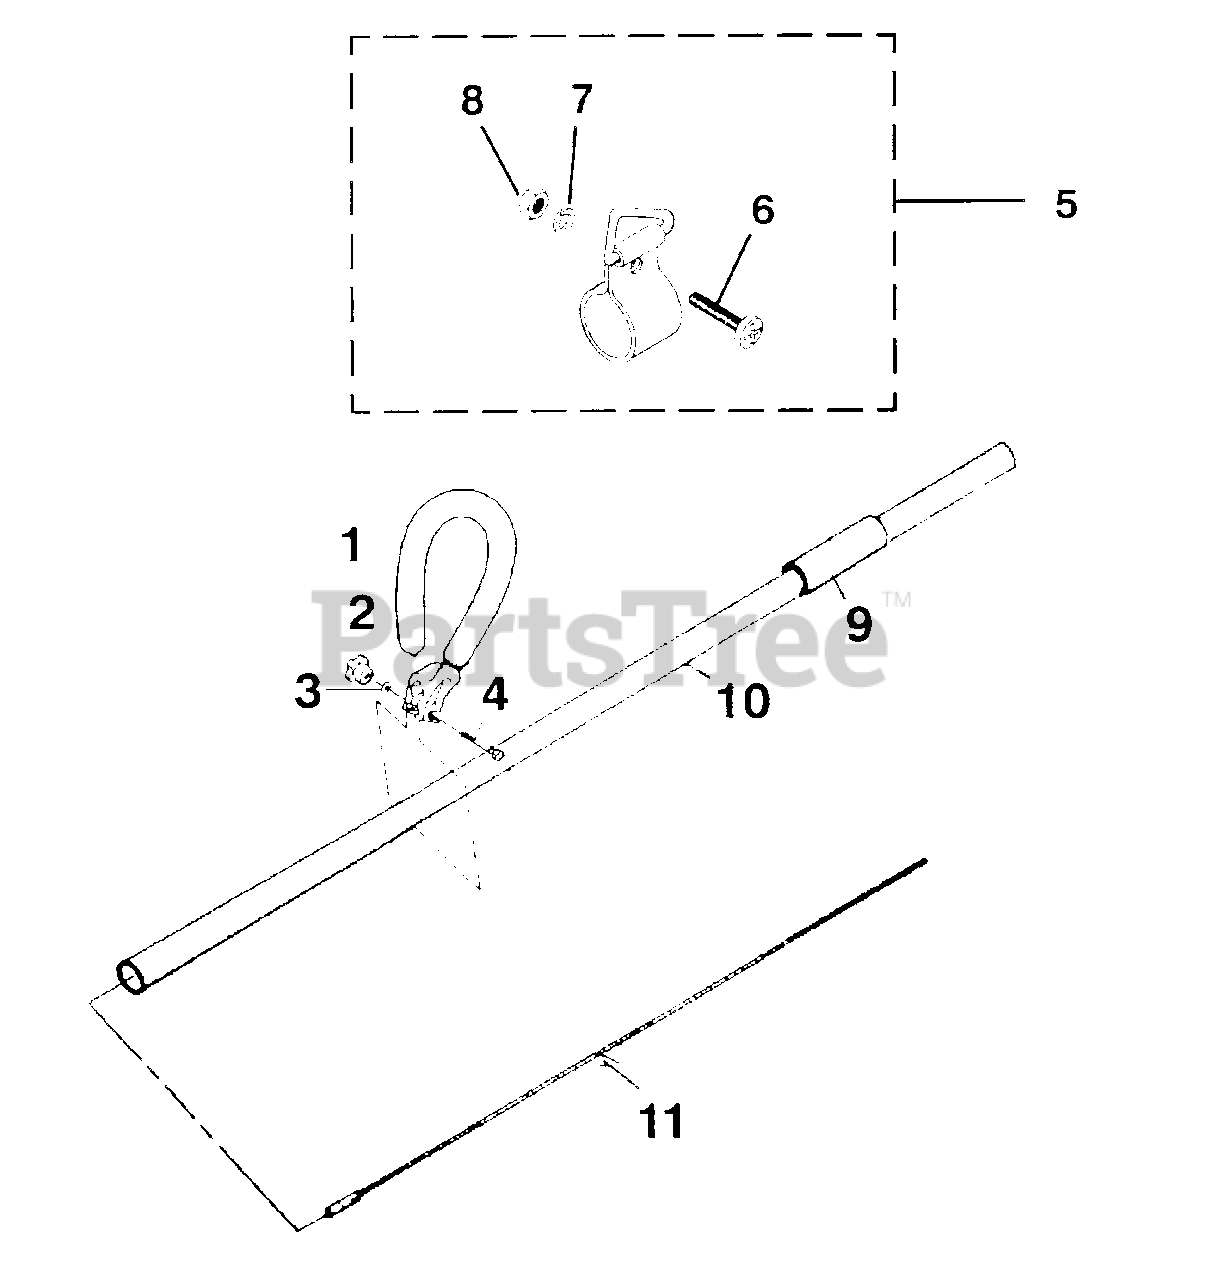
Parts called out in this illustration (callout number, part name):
1	HANDLE ASSY
4	BOLT, HEX
5	HANGER ASSY
8	NUT
11	FLEX CABLE
